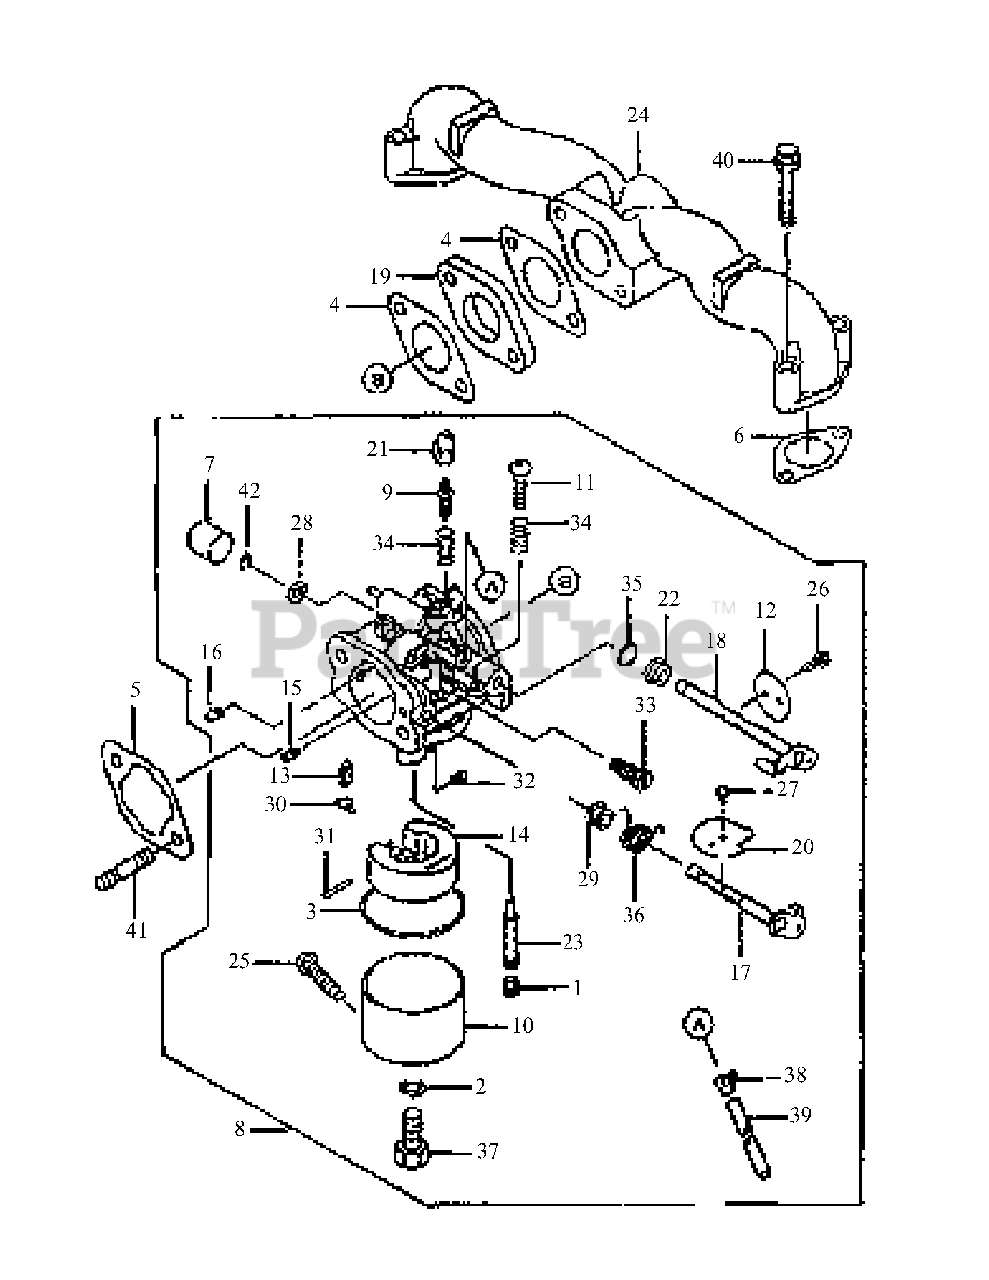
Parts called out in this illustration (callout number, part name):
4	Gasket, Insulator
5	Gasket, Air Filter
9	Screw, Pilot Air
10	Chamber, Float
11	Screw, Throttle Stop
12	Valve, Throttle #130
15	Jet, Air #1.6
16	Jet, Air #0.8
18	Shaft, Throttle
19	Insulator
23	Nozzle Main #111A
24	Manifold, Intake
32	Jet, Main #110
39	tube, 4.5x6.5x100
40	Bolt, Flange
42	Circlip, Type E
